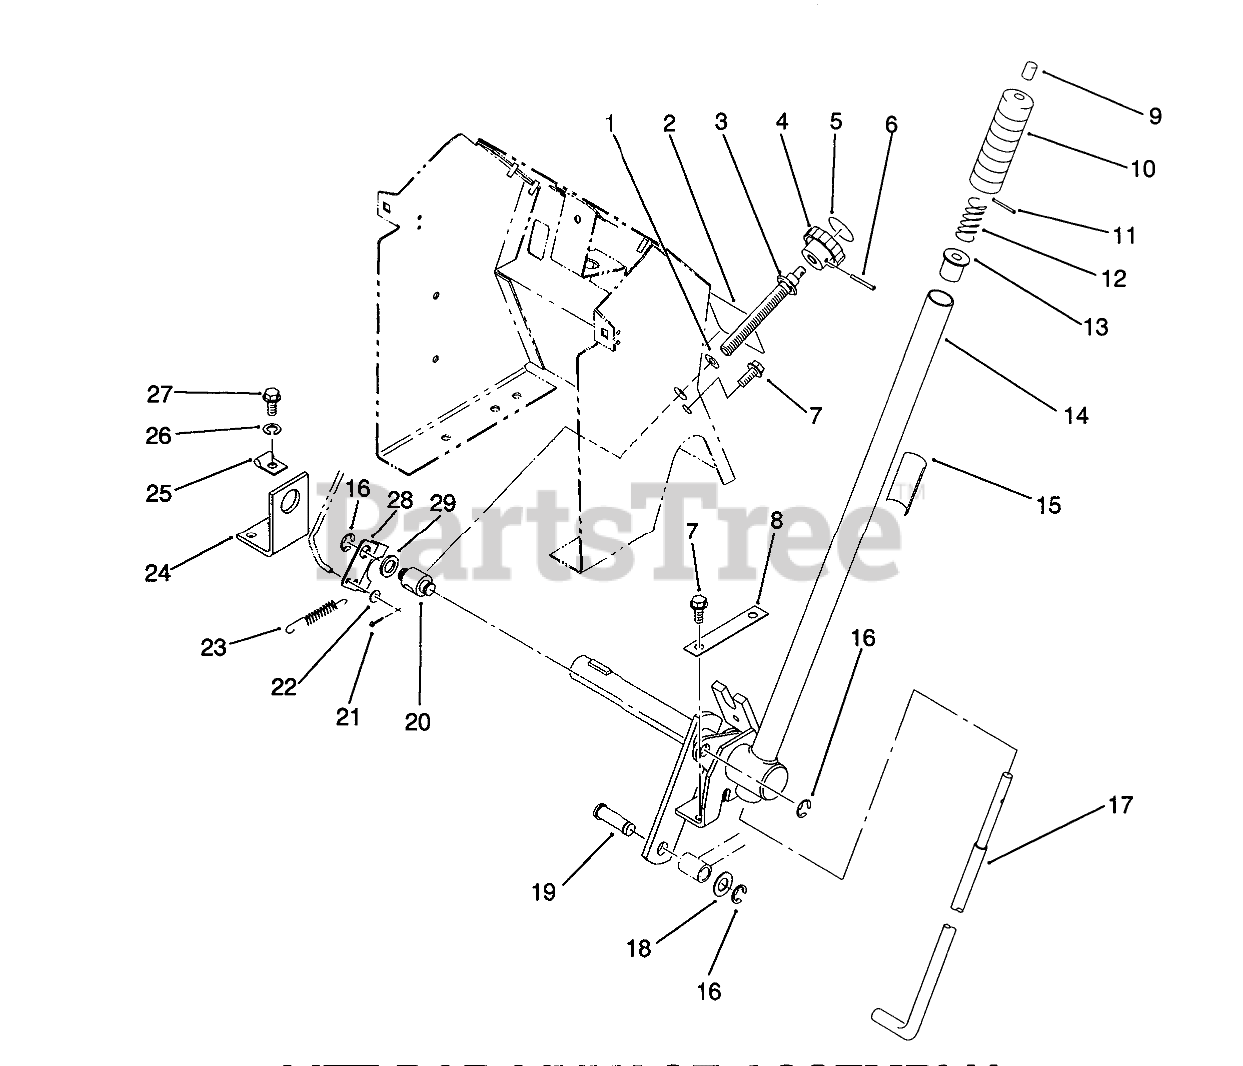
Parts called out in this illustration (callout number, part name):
1	WASHER
2	Decal
3	ROD B
5	DECAL-HEIGHT KNOB
6	Pin-Roll
7	Screw
8	Plate
9	CAP-ROD, PLUNGER
10	HANDGRIP
11	PIN-SPIROL
12	SPRING-COMPRESSION
13	RETAINER-SPRING
14	Handle
15	DECAL-LIFT
16	E Ring
17	ROD-LATCH LIFT
18	Washer
19	SUPPORT-INDICATOR B
20	TRUNNION
21	Pin-Cotter
22	Washer
23	SPRING-EXTENSION
24	BRACKET B
25	THROTTLE CONTROL CLP
26	Washer-Lock
27	Screw
28	PLATE B
29	WASHER
